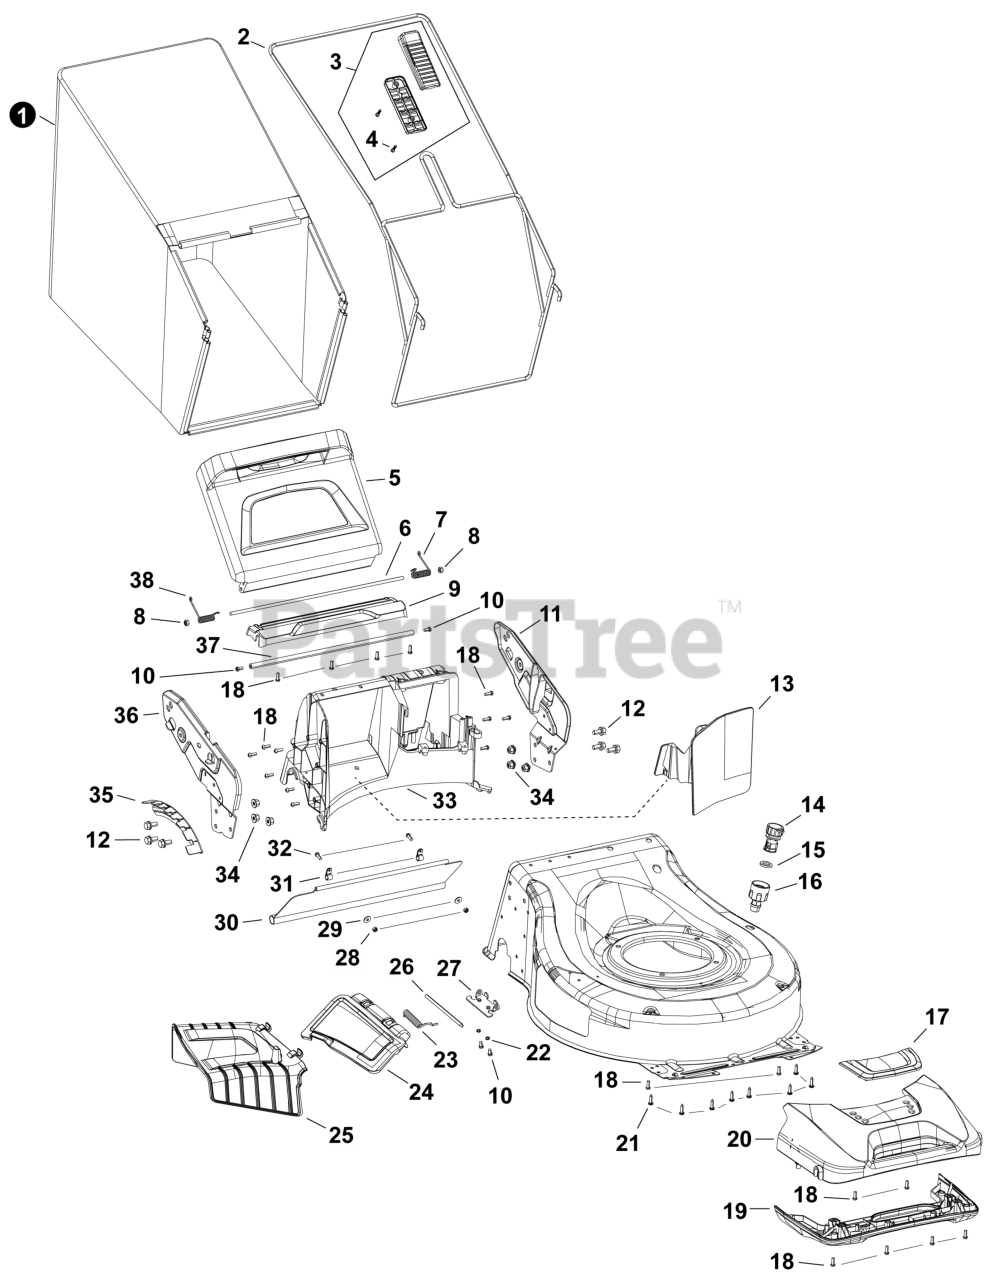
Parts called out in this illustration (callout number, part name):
1	BAG, GRASS
2	FRAME, GRASS BAG
3	HANDLE KIT, GRASS BAG
4	SCREW
4	COVER, REAR DISCHARGE
5	ROD, REAR DISCHARGE COVER
5	COVER, REAR DISCHARGE
6	ROD, REAR DISCHARGE COVER
6	SPRING, RIGHT REAR DOOR
7	SPRING, RIGHT REAR DOOR
8	PLATE, REAR COVER MOUNTING
9	PLATE, REAR COVER MOUNTING
10	BRACKET, LEFT HANDLEBAR
11	BRACKET, LEFT HANDLEBAR
12	PLUG, MULCH
13	ADAPTOR, HOSE
13	PLUG, MULCH
14	ADAPTOR, HOSE
15	PORT, HOSE
16	PORT, HOSE
16	COVER, DECORATIVE
17	COVER, DECORATIVE
18	BASE, FRONT COVER
19	COVER, FRONT
19	BASE, FRONT COVER
20	COVER, FRONT
21	PLATE, SIDE COVER MOUNTING
23	ROD, SIDE DISCHARGE COVER
23	SPRING, SIDE DISCHARGE COVER
24	COVER, SIDE DISCHARGE
24	SPRING, SIDE DISCHARGE COVER
25	COVER, SIDE DISCHARGE
25	CHUTE, SIDE DISCHARGE
26	ROD, SIDE DISCHARGE COVER
26	CHUTE, SIDE DISCHARGE
27	KIT, DEBRIS SHIELD
27	PLATE, SIDE COVER MOUNTING
28	NUT
29	WASHER
30	SHIELD, DEBRIS
31	CLAMP
32	SCREW
33	BAFFLE, REAR
35	PLATE, HEIGHT ADJUSTMENT
36	BRACKET, RIGHT HANDLEBAR
37	ROD, HANDLEBAR BRACKET
38	SPRING, LEFT REAR DOOR
